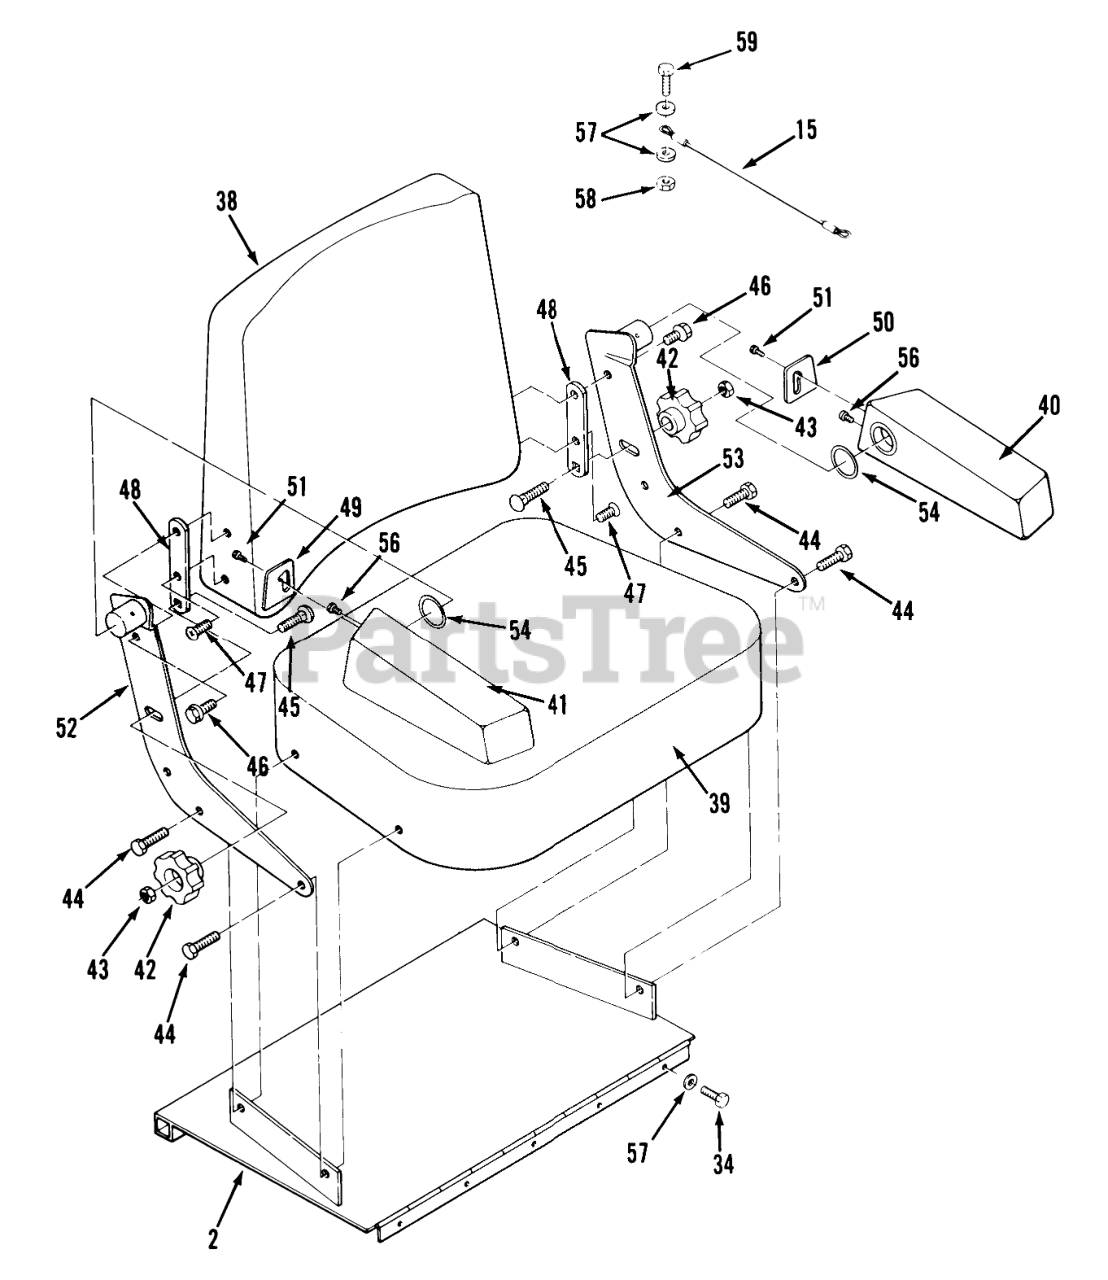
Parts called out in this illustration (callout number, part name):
2	Seat Mounting Bracket
15	Seat Cable
34	Bolt
38	Seat Back
39	Seat Bottom
40	ARM REST LH
41	ARM REST RH
42	Knob-Lumbar Control
43	LOCK NUT
44	Bolt
45	Bolt
47	Screw-Phillips Hd
48	Lumbar Friction Plate
49	ARM REST PLATE RH
50	ARM REST PLATE LH
51	SCREW PAN HD 10-16X5
52	BACK SUPT LH
53	Back Support LH
54	WASHER
56	SHCS 1/4-20 X 1/2
57	WASHER
58	Nut 1/4-20
59	Bolt
